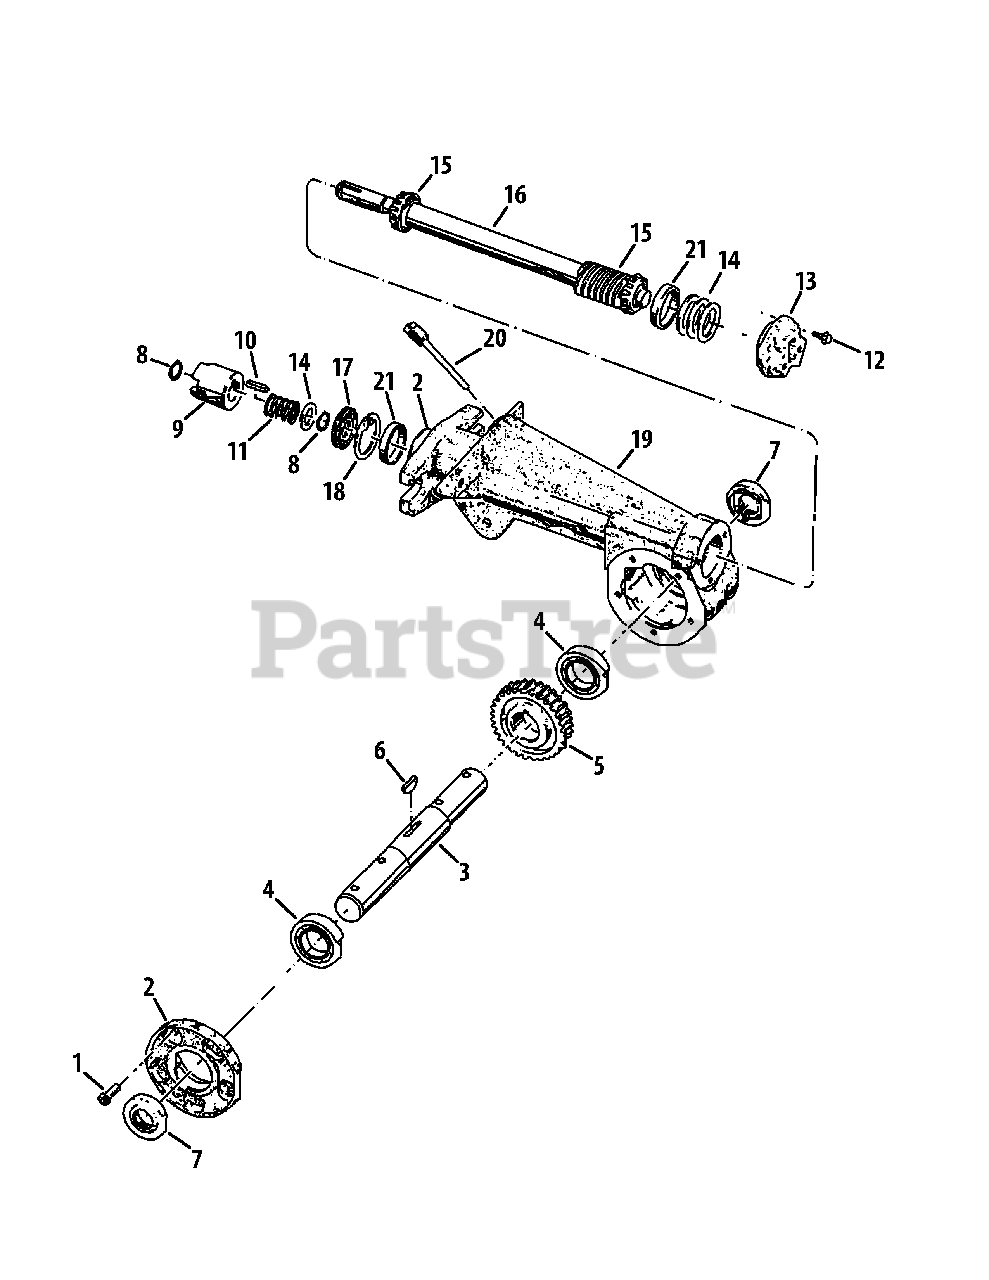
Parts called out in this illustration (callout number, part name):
1	Self-Sealing Screw, 1/4"-20 x 5/8"
2	Tiller Housing Cover
3	Tine Shaft
4	Ball Bearing
5	Worm Gear
6	Woodruff Key
8	External Retaining Ring
9	Dog Clutch
10	Key, 3/8" x 1"
12	Self-Sealing Screw, 1/4"-20 x 7/8"
14	Flat Washer, 1.75 x 1.5 x .062
14	Flat Washer, 1.75 x 1.5 x .005
14	Flat Washer, 1.75 x 1.5 x .03
14	Flat Washer, 1.75 x 1.5 x .01
15	Cup Bearing
18	Retaining Ring
19	Attachment Housing
20	Oil Dipstick
21	Cone Bearing
